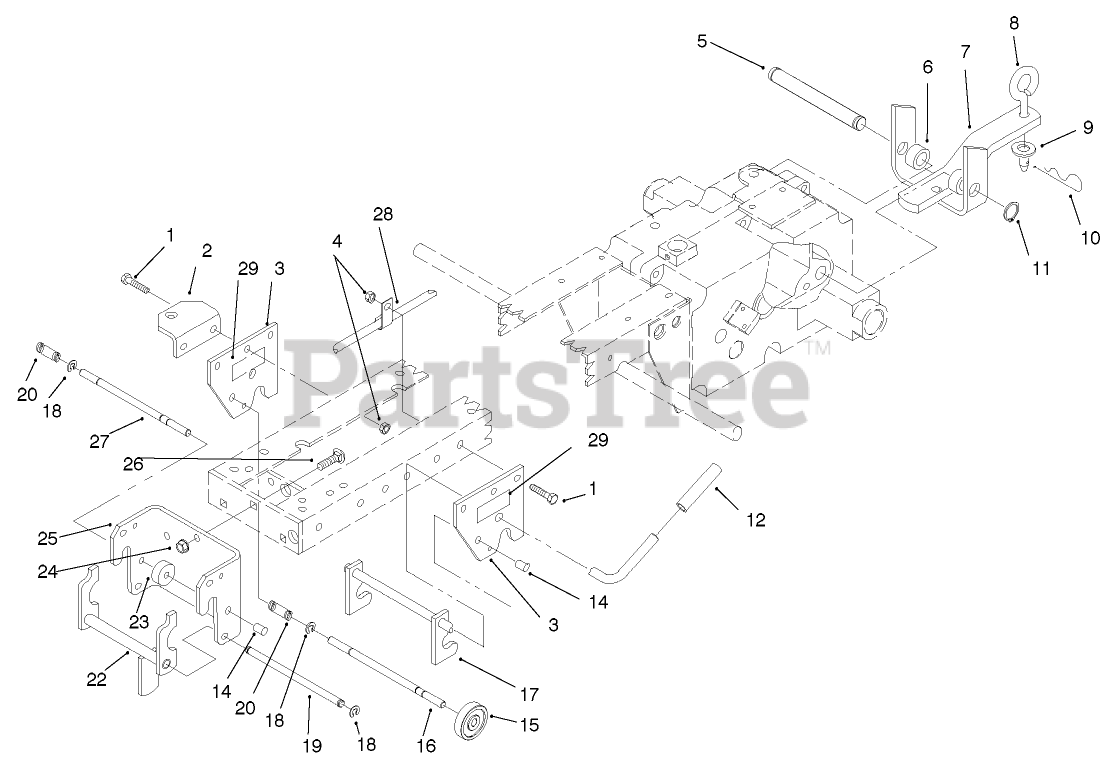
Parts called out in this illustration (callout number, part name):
1	SCREW-HH
2	SUPPORT
3	PLATE-HITCH
4	NUT-HEX
5	PIN-STATIONARY HITCH
6	SPACER
8	PIN-TOOL
9	WASHER-FLAT
10	PIN-HAIR
11	E-RING
12	GRIP
14	CAP-ROD, PLUNGER
16	ROD-LOCK
17	MID HITCH ASM
18	RING-RETAINING
19	ROD-LATCH PIVOT
20	SPRING
22	LATCH
24	NUT-LOCK, NI
25	HITCH-FRONT
26	BOLT-CARR
27	ROD-LOCK
28	CLIP
29	DECAL-ATTACH A-MATIC
